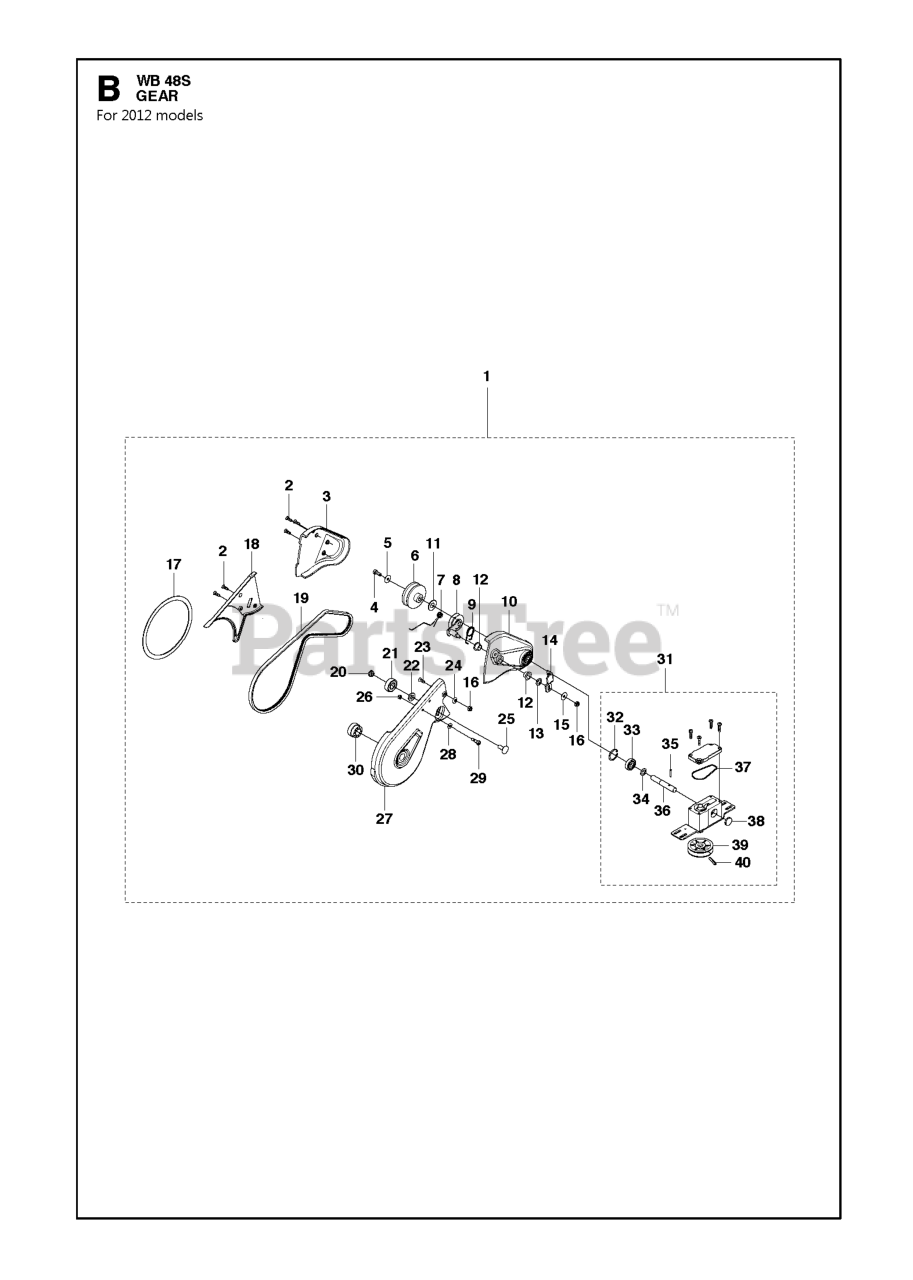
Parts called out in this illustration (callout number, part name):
15	WASHER 19X6X1
16	NUT FLANGE - M6
21	BALL BEARING 6201-2RS1
33	BALL BEARING
